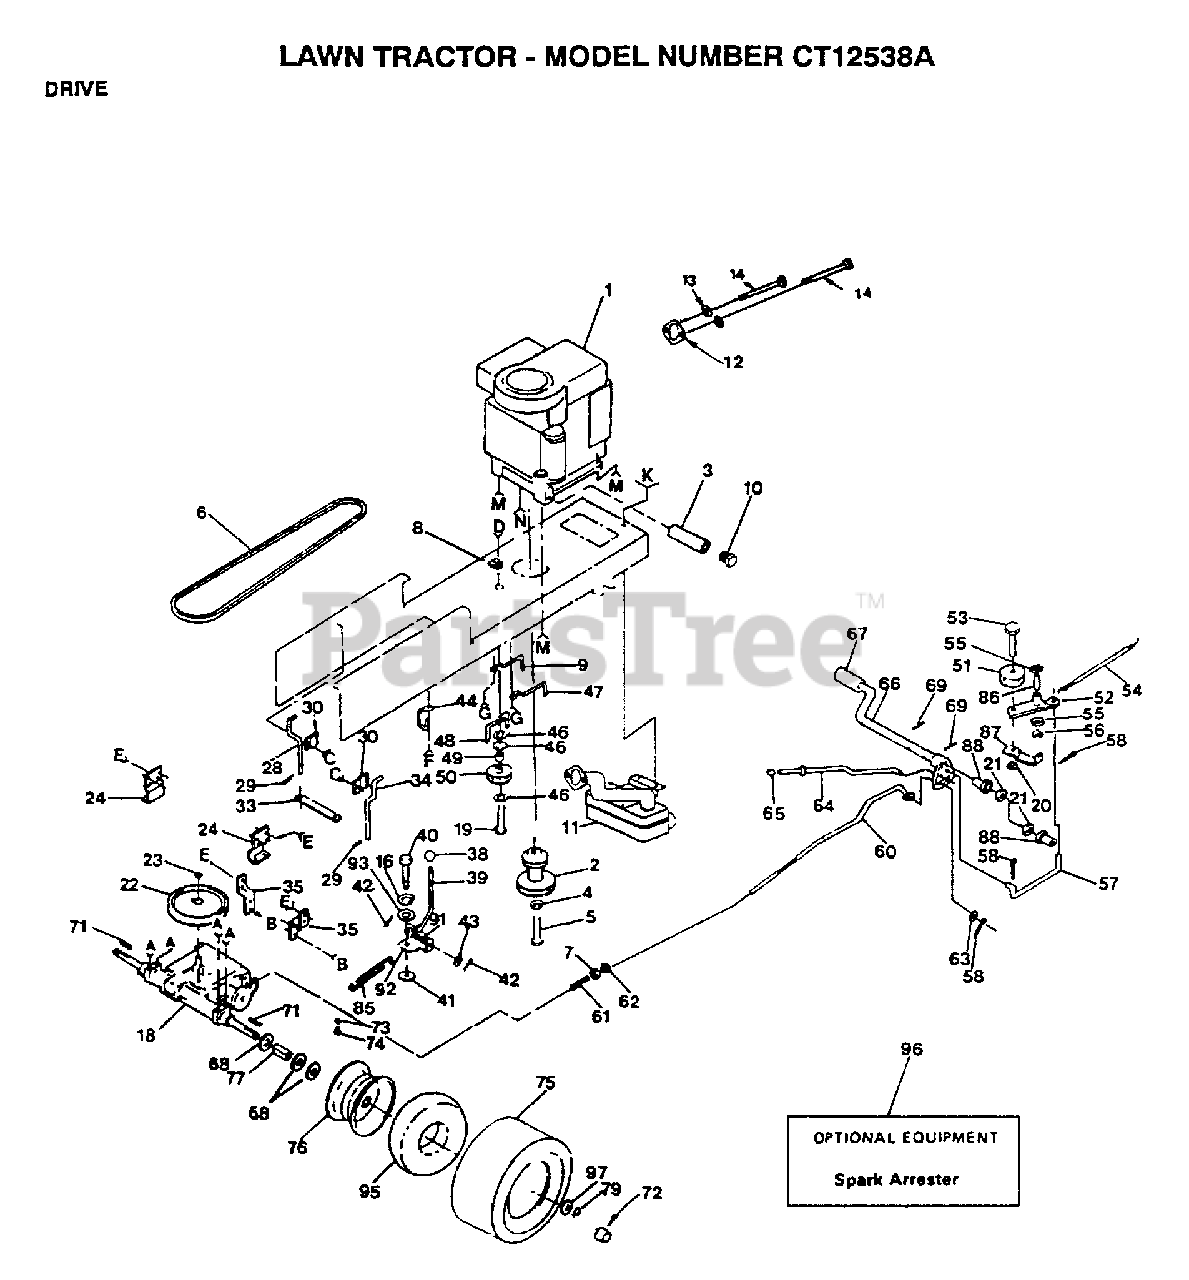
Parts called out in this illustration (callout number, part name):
4	LOCKWASHER
5	BOLT
6	BELT-V.90.0.GD.DR
7	NUT
8	CLIP T
9	KEEPER BELT ENGLH
11	MUFFLER
13	LOCKWASHER
14	SCREW LT
16	LOCKWASHER
21	WASHER LT
22	PULLEY TRANS
24	BRACKET LT
28	KEEPER BELT LH
29	SPRING.RETAINER
30	CLAMP LT
33	STRAP LOCATOR
34	KEEPER BELTRH
35	STRAP TORQUE
38	CONTROL KNOB LT
39	ROD SHIFTER
41	WASH-SHFT PLT LT
42	PIN COTTER 1/8
43	WASHER
46	WASHER
47	"KEEPER,BLT ENG LT"
48	BELT KEEPER LT
49	SPACER T
50	PULLEY.IDLER.FLAT
52	ARM IDLER
54	"SPRING, RETURN LT"
55	WASHER LT
56	KLIP RING
57	"LINK, CLUTCH T"
58	COTTER PIN
60	BRAKE ROD LT
61	SPRING ROD LT
62	NUT
63	WASHER
67	PEDAL COVER T
68	WASHER
71	SQUARE KEY
72	HUB CAP
73	VALVE CAP
74	VALVE STEM LT
77	SPACER LT
79	E-RING LT
86	"LY, BEARING"
87	RETAIN BELT
88	NYLON BEARING
91	SPRING LT
92	PLATE SHIFT LT
93	WASHER LT
95	TUBE.18X9.5-8
97	WASHER
